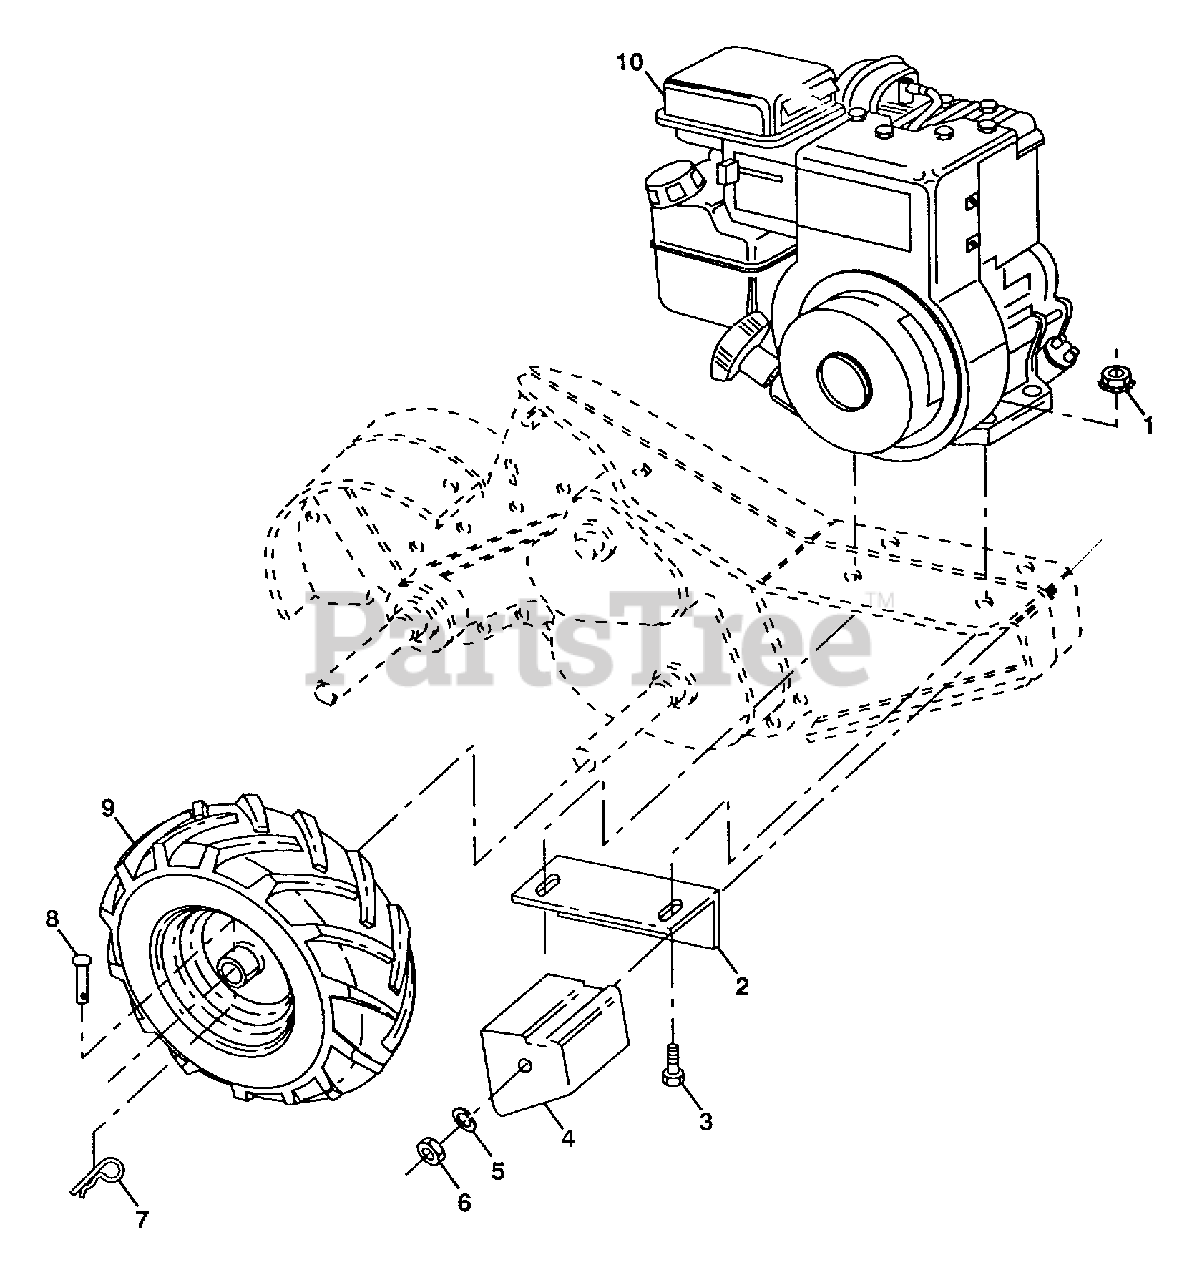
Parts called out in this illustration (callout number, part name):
2	BRACKET RH CRT
3	BOLT.HEX.5/16-1.5
4	COUNTERWEIGHT CRT
5	LOCKWASHER
6	NUT.HEX.3/8-16UNC
7	RETAINER M
8	RIVET.DRILL.1.75
9	TIRE TI
